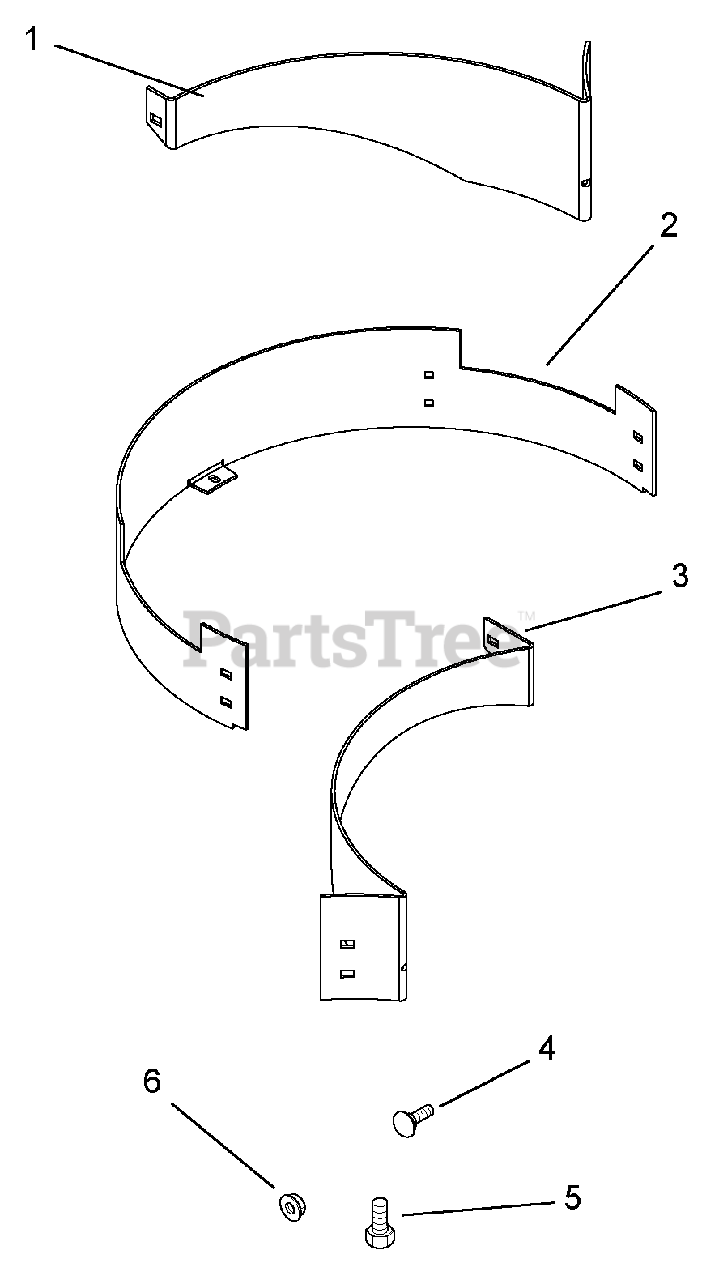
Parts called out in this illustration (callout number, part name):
1	BAFFLE-MULCH-LEFT REAR-52" RD
1	Discharge Mulch Baffle
1	BAFFLE - LEFT MULCH - 60"
1	BAFFLE-MULCH-LEFT REAR-72" RD
2	BAFFLE-MULCH-CENTER REAR-52"RD
2	Discharge Mulch Baffle
2	BAFFLE - MIDDLE MULCH - 60"
2	BAFFLE-MULCH-CENTER REAR-72"RD
3	BAFFLE-MULCH-RIGHT REAR-52" RD
3	Discharge Mulch Baffle
3	BAFFLE -RIGHT MULCH - 60"
3	BAFFLE-MULCH-RIGHT REAR-72" RD
4	@BLT-RDHDSQNK .31-18X.75 G5YZ
4	Square Neck Bolt
5	@BLT-HEX .31-18X.75 GR5 YWZC
6	@NUT-LK-TOP-FLG .31-18 YWZC
6	KIT-52" MULCH-REAR DISCHARGE
6	KIT,60"REAR DISCH MULCH
6	KIT-72" MULCH-REAR DISCHARGE
